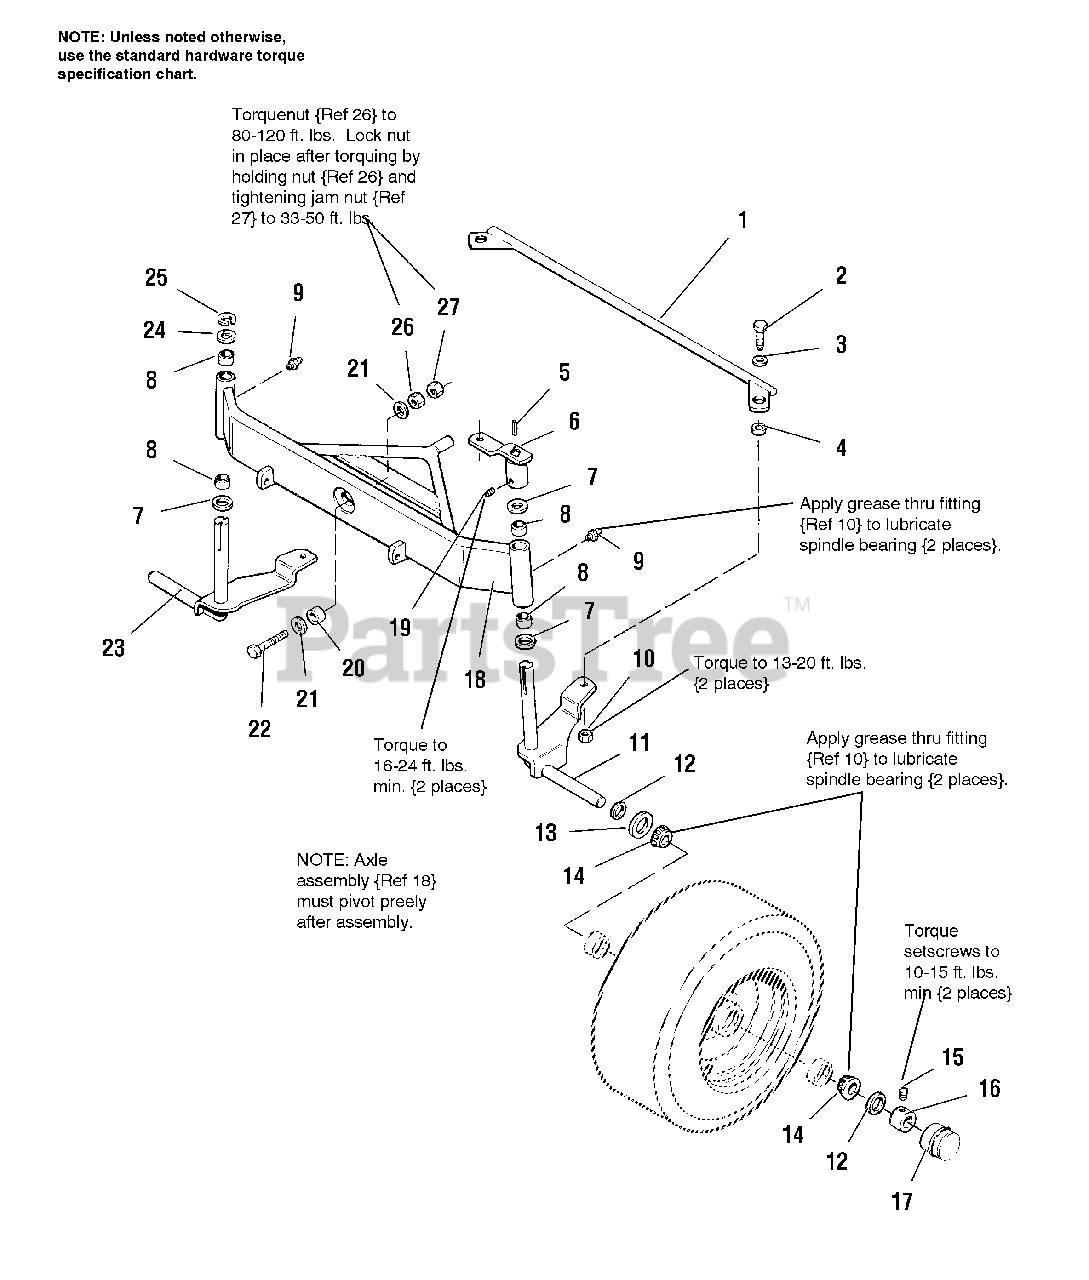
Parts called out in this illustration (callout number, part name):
1	ROD ASSEMBLY, Tie
2	CAPSCREW, Hex Hd, 3/8-16 x 1
3	WASHER, Plain, 3/8
5	KEY, Square, 3/16 x 1-1/4
6	ARM ASSEMBLY, Steering
7	WASHER
9	FITTING, Grease
10	LOCKNUT, Hex, 3/8-16
11	SPINDLE ASSEMBLY, LH
14	CONE, Bearing
15	SETSCREW, 5/16-18 x 5/16
16	COLLAR, Set
17	CAP, Hub
18	AXLE ASSEMBLY, Front
19	SETSCREW, Hex Socket Hd, 3/8-16 x 1/2
21	WASHER, Plain, 1/2
22	CAPSCREW, Hex Hd, 1/2-13 x 2-1/4
23	SPINDLE ASSEMBLY, RH
25	RING, Retaining
26	LOCKNUT, Hex, 1/2-13
27	LOCKNUT, Hex, Jam, 1/2-13
